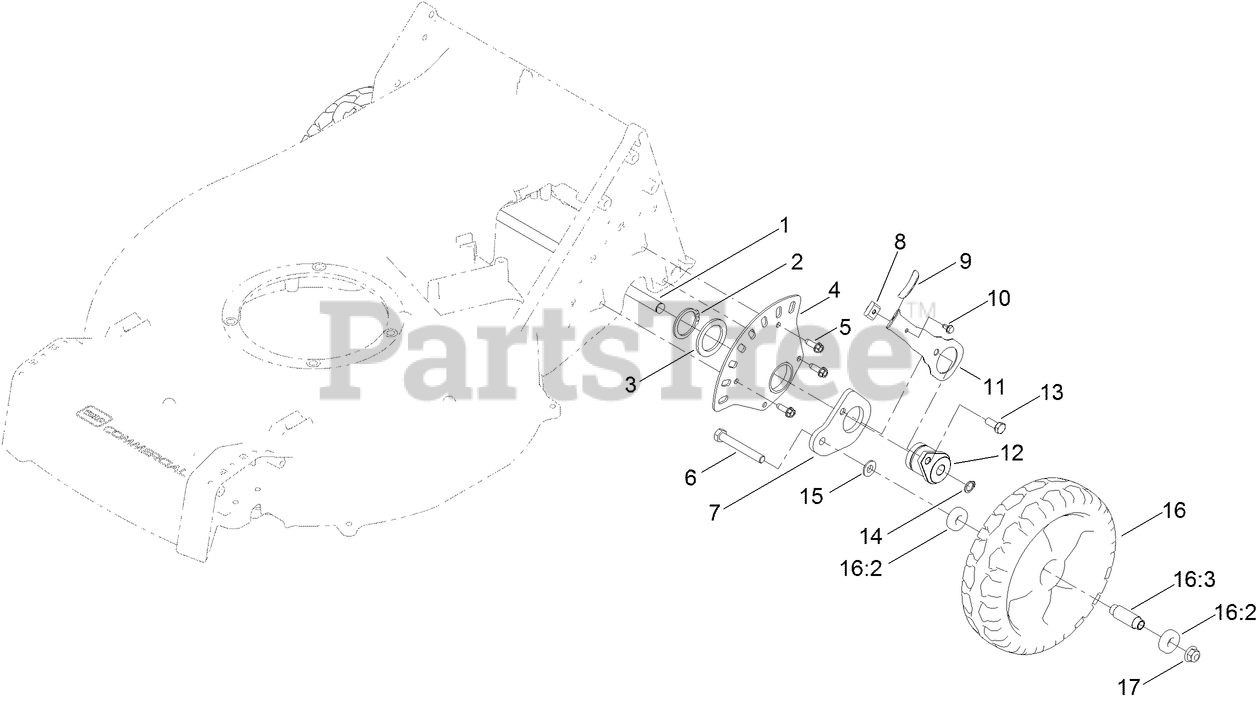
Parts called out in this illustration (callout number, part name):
1	SHAFT-REAR, HOC
2	RING-RETAINING
3	WASHER-THRUST
4	PLATE-HOC, REAR
5	SCREW-HWHTF
6	SCREW-HH
7	ARM-PIVOT, REAR
8	KEY-ARM, SPRING
9	KNOB-LEVER, HOC
10	SCREW-HWH
11	ARM-SPRING, REAR
12	RETAINER-REAR, HOC
13	SCREW-HH
14	RING-RETAINING
15	SPACER-COVER, WHEEL
16:2	BEARING-BALL
16:3	SPACER
17	NUT-HF, NI
